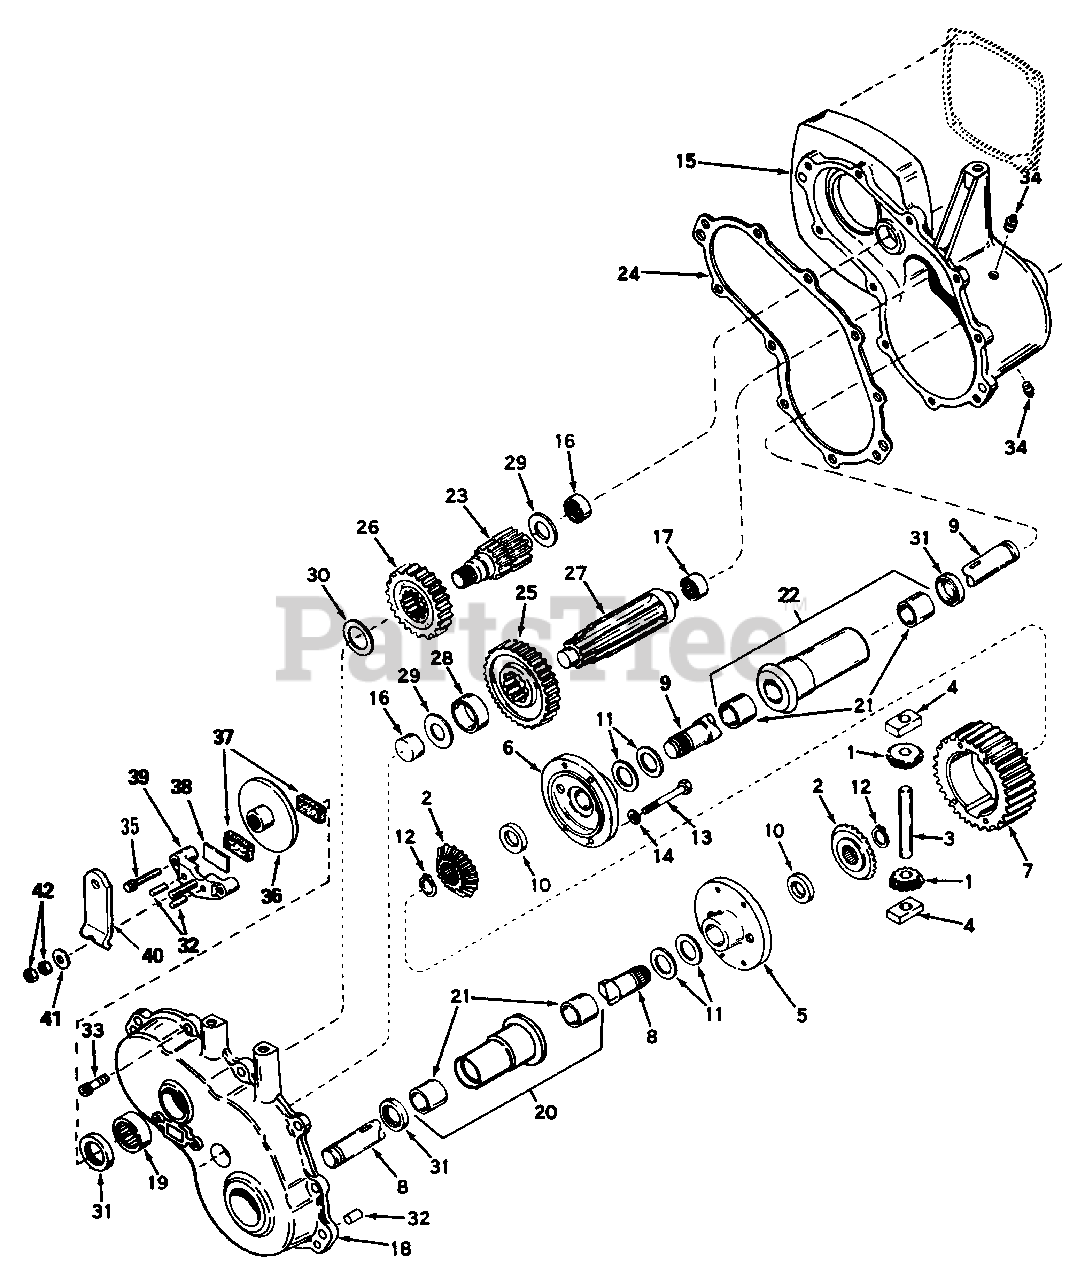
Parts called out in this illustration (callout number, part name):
1	PINION, Bevel
2	GEAR, Bevel
3	PIN, Drive
4	BLOCK, Drive
5	CARRIER, Differential
6	CARRIER, Differential
7	GEAR, Ring
8	AXLE (12-3/4" long)
9	AXLE (14-23/32" long)
11	WASHER, Thrust
12	RING, Snap
13	SCREW, Hex Hd., 1/4-20 x 2-1/4
14	LOCKWASHER, 1/4"
15	CASE ASSY. (Incl. Nos. 16 & 17)
16	BEARING, Needle
17	BEARING, Needle
18	COVER ASSY. (Incl. Nos. 16 & 19)
19	BEARING, Needle
20	HOUSING & BUSHING ASSY. (6-5/8" long)(Incl. 2 of No. 21)
22	HOUSING & BUSHING ASSY. (8-5/8" long)(Incl. 2 of No. 21)
23	SHAFT, Brake
24	GASKET, Case-to-Cover
25	GEAR, Output
26	GEAR, Idler
27	SHAFT, Output
31	SEAL, Oil
32	PIN, Dowel
33	SCREW, Hex Wash. Hd., Thd. Form., 1/4-20 x 1
34	PLUG, Pipe
35	SCREW, Hex Hd., Thd. Form., 1/4-20 x 1-1/4
36	DISK, Brake
37	PAD, Brake
38	PLATE, Brake Pad
39	HOLDER, Brake Pad
40	LEVER, Brake
41	WASHER, Flat
42	LOCKNUT, 5/16-24
